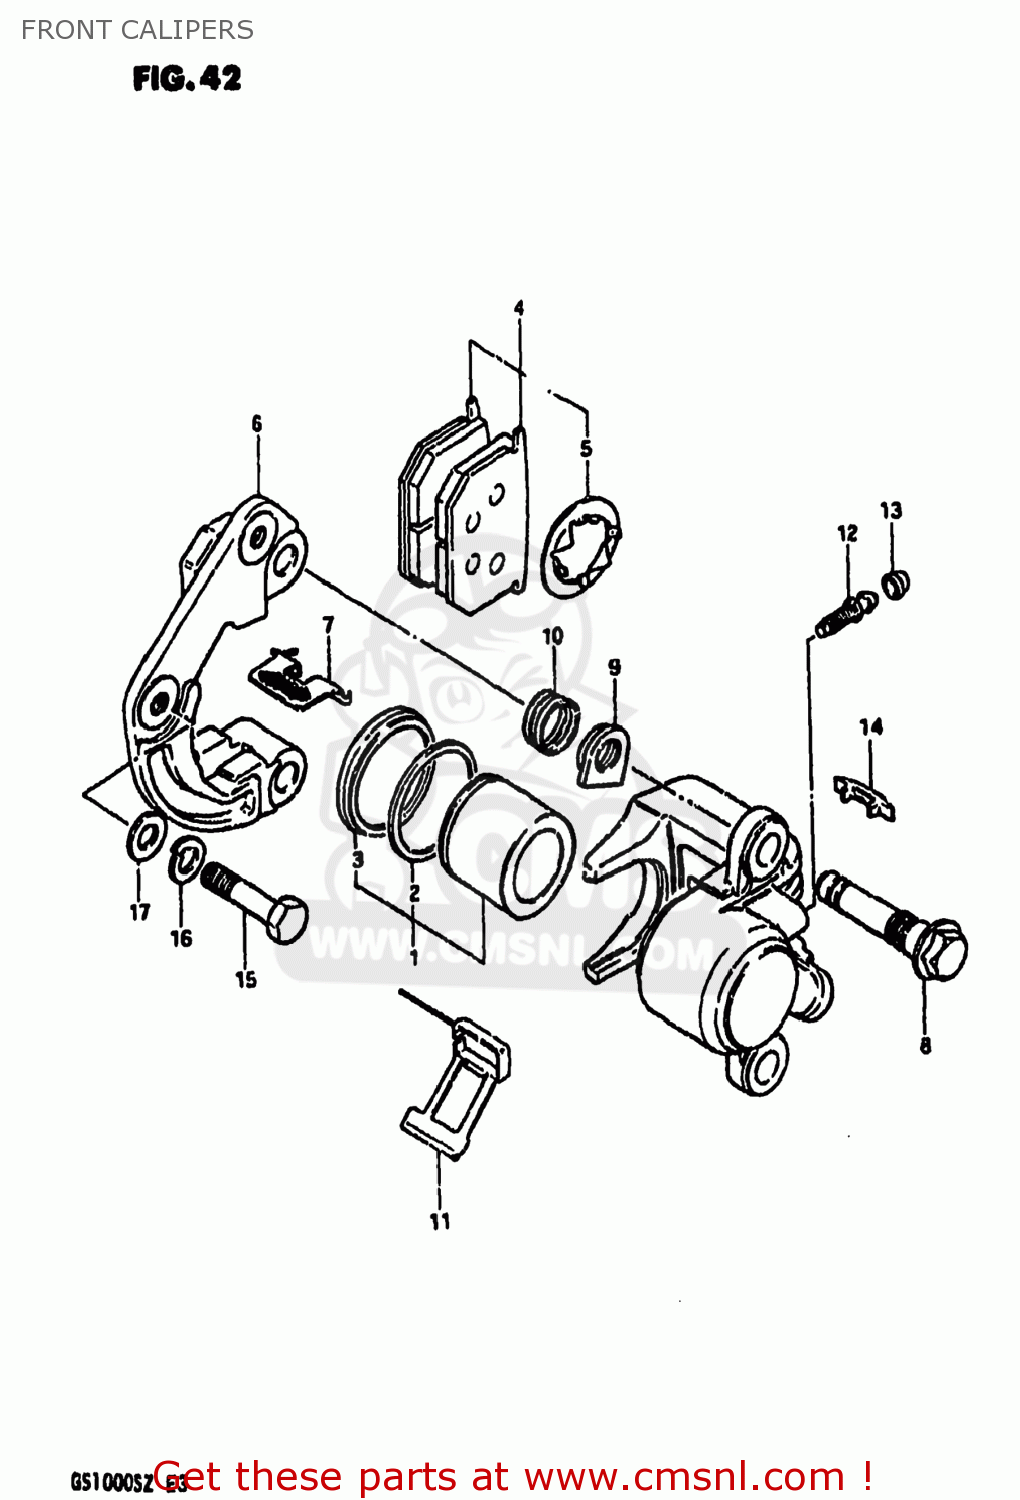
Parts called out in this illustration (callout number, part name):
0	CALIPER ASSEMBLY,LEFT
1	PISTON SET
2	SEAL,PISTON
3	BOOT,PISTON
4	PAD & SHIM SET (MCA)
5	SHIM,PAD
6	HOLDER,CALIPER,LEFT
7	PAD,GUIDE
8	AXLE,CALIPER
9	NUT,CALIPER AXLE
10	BOOT
11	SPRING
12	BREATHER
13	CAP,BLEEDER PL
14	COVER,INDICATOR
15	BOLT
16	LOCK WASHER
17	WASHER
